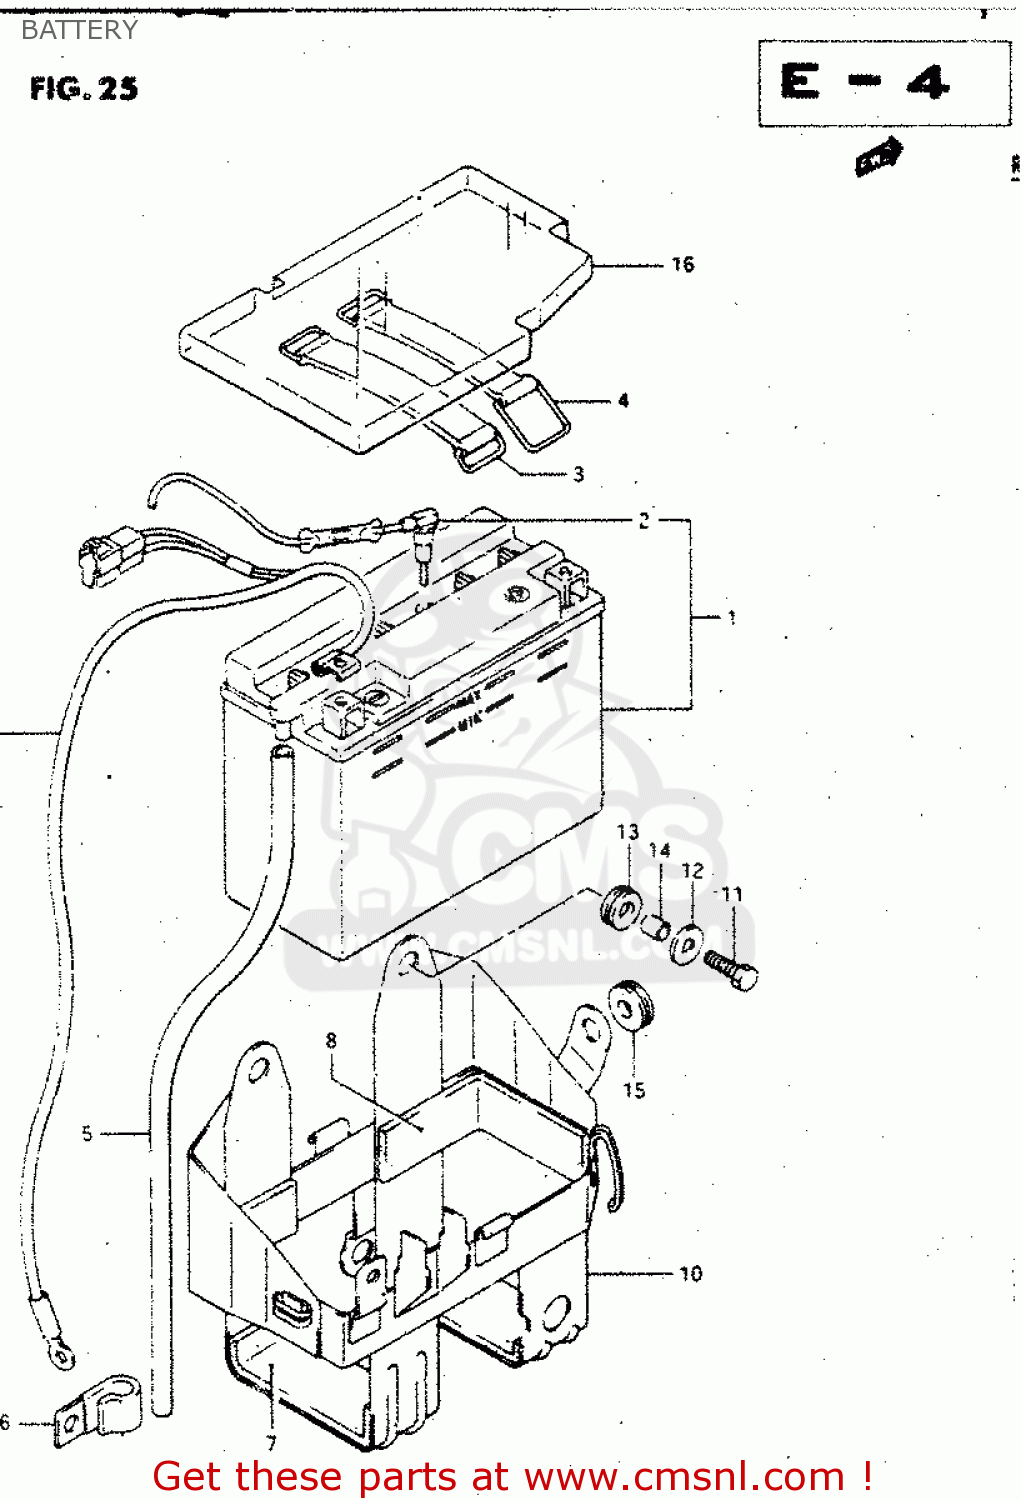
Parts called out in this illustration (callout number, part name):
1	BATTERY ASSEMBLY
2	SENSOR, BATTERY LEVEL
3	BAND
4	BAND
5	HOSE,BATTERY EXHAUST(L:780)
6	CLAMP
7	PROTECTOR(170X95X3.0)
8	PROTECTOR(170X95X3.0)
9	WIRE,BATTERY MINUS
10	HOLDER,BATTERY
11	BOLT,M6X1X20
12	WASHER
13	CUSHION
14	SPACER(6.2X9X7.5)
15	CUSHION
16	COVER,BATTERY
